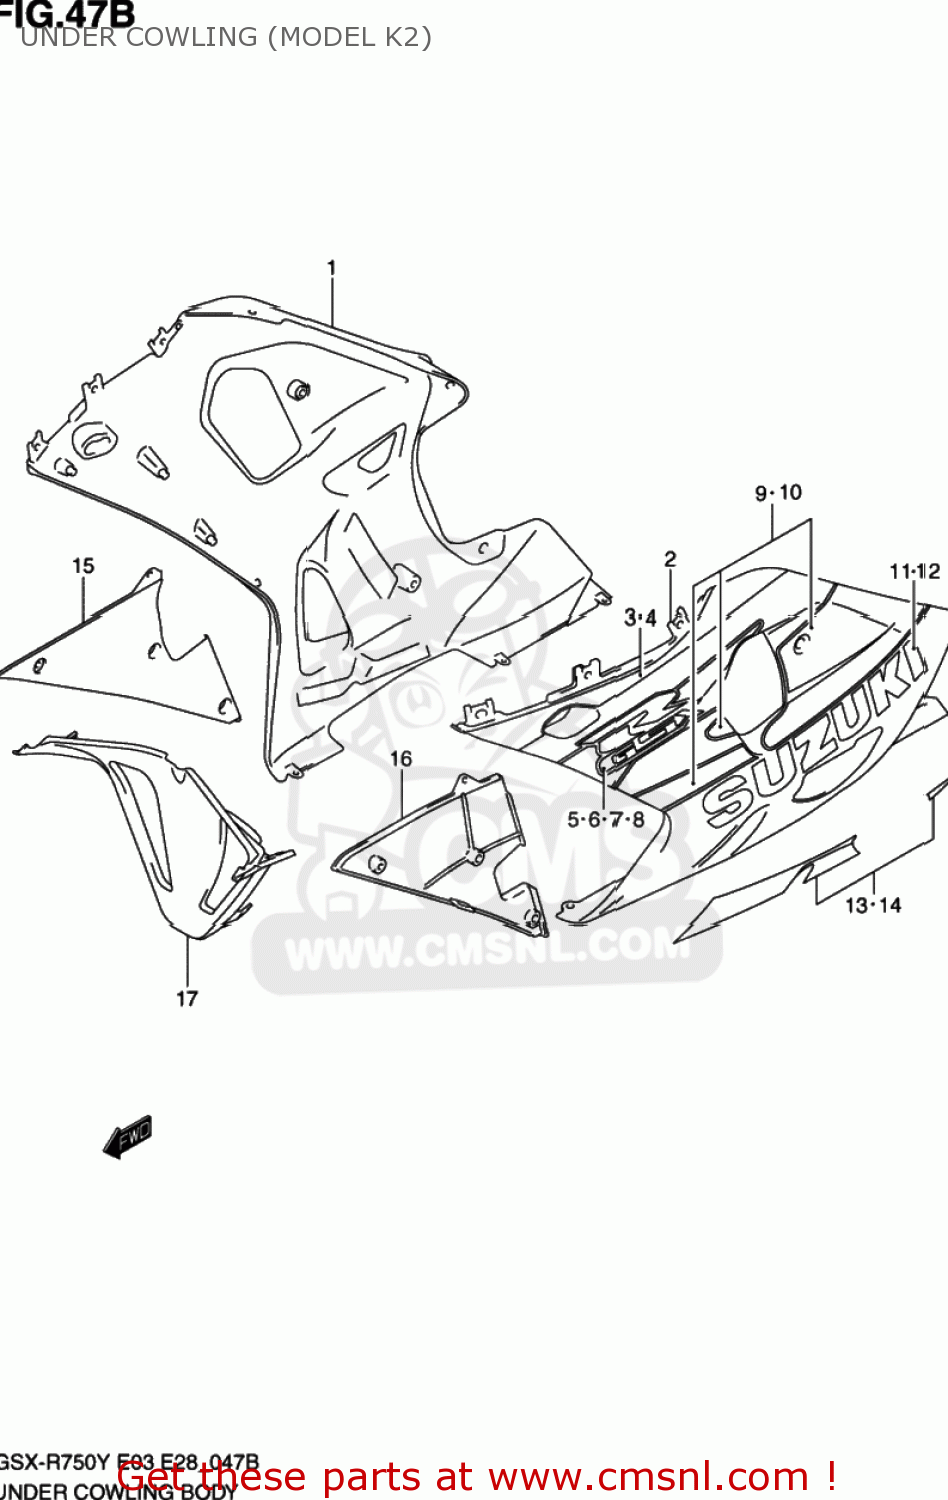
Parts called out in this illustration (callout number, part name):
1	COWLING ASSY,UNDER,R
2	COWLING ASSY,UNDER,L
3	TAPE,COWL UNDER UPR,R
4	TAPE,COWL UNDER UPR,L
5	TAPE(GSXR),COWL UNDER,R
6	TAPE(GSXR),COWL UNDER,R
7	TAPE(GSXR),COWL UNDER,L
8	TAPE(GSXR),COWL UNDER,L
9	TAPE SET,COWL MIDDLE,R
10	TAPE SET,COWL MIDDLE,L
11	EMBLEM SET,SUZUK,R
12	EMBLEM SET,SUZUK,L
13	TAPE SET,COWL LWR,R
14	TAPE SET,COWL LWR,L
15	COWLING,UNDER INNER,R
16	COWLING,UNDER INNER,L
17	COWLING,UNDER CTR
